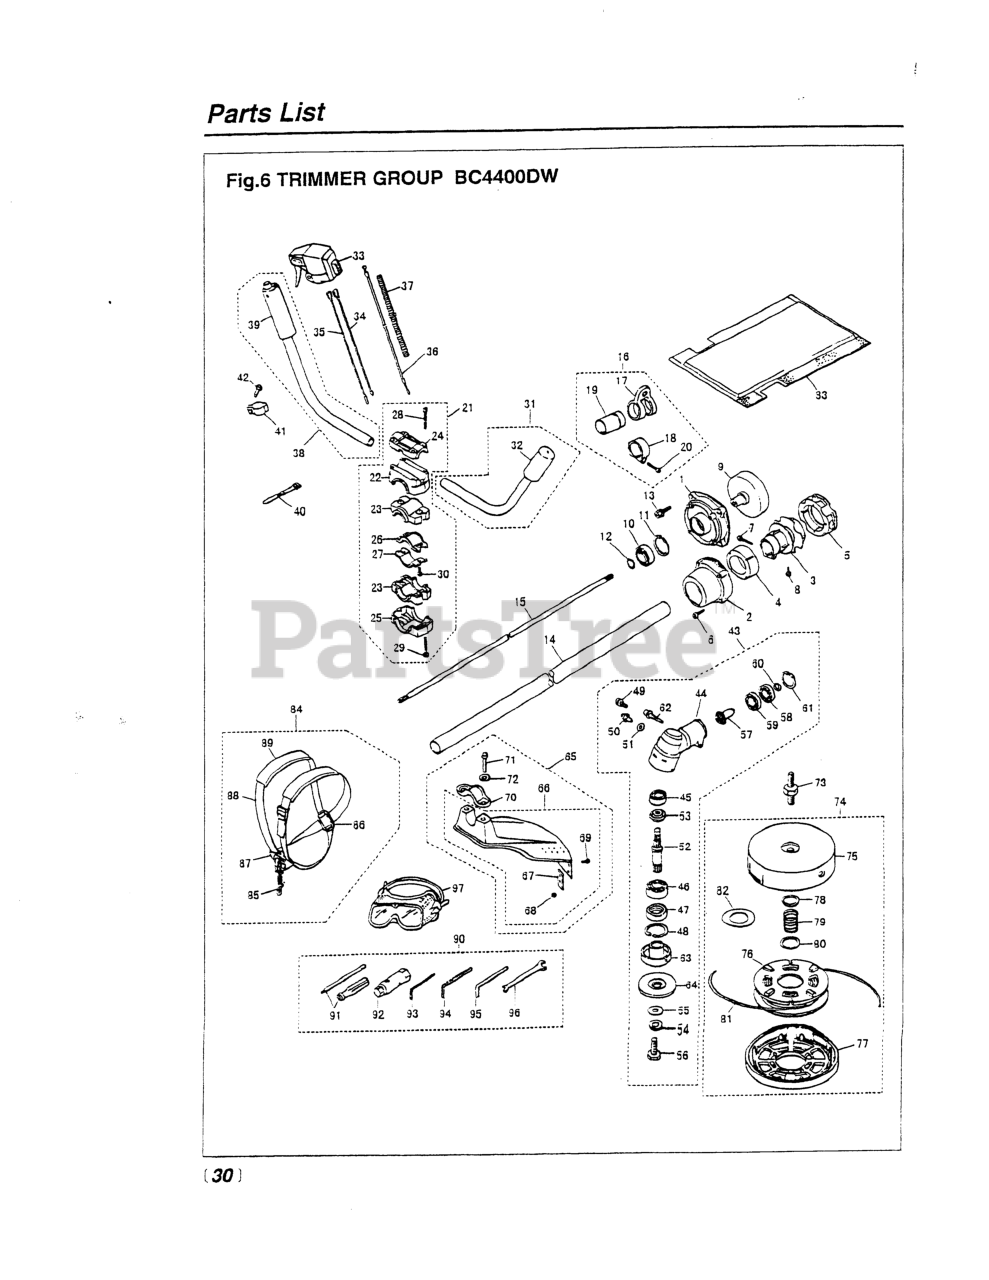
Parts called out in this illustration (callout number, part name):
1	HOUSING
2	CAP
3	JOINT
4	ABSORBER-F
5	ABSORBER-R
6	BOLT, M5 X 30
7	BOLT, M6 x 30
8	BOLT, M5 X 10
10	BEARING
11	RING, SNAP, M35 X 1.5
12	RING, SNAP, M15 X 1.0
13	BOLT, M6 x 20
14	PIPE COMPLETE
15	SHAFT (USE -12212)
16	HANGER ASSEMBLY
17	HANGER
18	CLAMP
20	SCREW, M5 x 25
23	ABSORBER
24	CAP, UPPER (RPLS -14191)
26	CLAMP (A)
27	CLAMP (B)
28	BOLT, M5 X 25
29	BOLT, M5 X 35
30	BOLT (USE 3310-31720)
31	HANDLE COMPL, LEFT
33	LEVER ASSEMBLY
34	CORD (A), BLACK
35	CORD (B), RED
37	TUBE
38	HANDLE COMPL, RIGHT
39	GRIP
40	BAND
41	CLAMP
42	SCREW, M5 X 16
44	GEARCASE (RPLS -13113)
45	BEARING (RPLS T3403-13510)
47	SEAL, OIL
48	RING, SNAP, M32 x 1.2
49	BOLT, M5 X 10
50	FITTING, GREASE
51	WASHER, M6 X .8
52	SHAFT
53	GEAR, BEVEL
54	WASHER (RPLS 3180-13270)
55	WASHER, M8 x 2.3 (RPLS -20823)
56	BOLT, LH
57	PINION
59	BEARING (RPLS T3403-13510)
60	RING, SNAP
61	RING, SNAP, M26 X 1.2
62	BOLT, M6 x 1.35
63	HOLDER (A)
64	HOLDER (B)
65	GUARD ASSEMBLY
66	GUARD COMP.
67	BLADE
68	NUT
69	SCREW, M5 x 12
70	CLAMP
71	BOLT, M6 x 1.30
72	WASHER, M6 X 15
73	SHAFT (RPLS 3274-99120)
74	6
75	CASE (USE -99112)
77	COVER
78	PLATE, LARGE
80	PLATE, SMALL
81	CORD
82	SPACER
83	PROTECTOR
87	HANGER COMP.
88	BAND (NOT SOLD SEPARATELY)
89	PROTECTOR
90	TOOL SET
91	SCREWDRIVER
93	WRENCH (TOOL)
94	WRENCH (TOOL)
95	BAR
96	SPANNER, 8 X 10 (RPLS 2540- )
